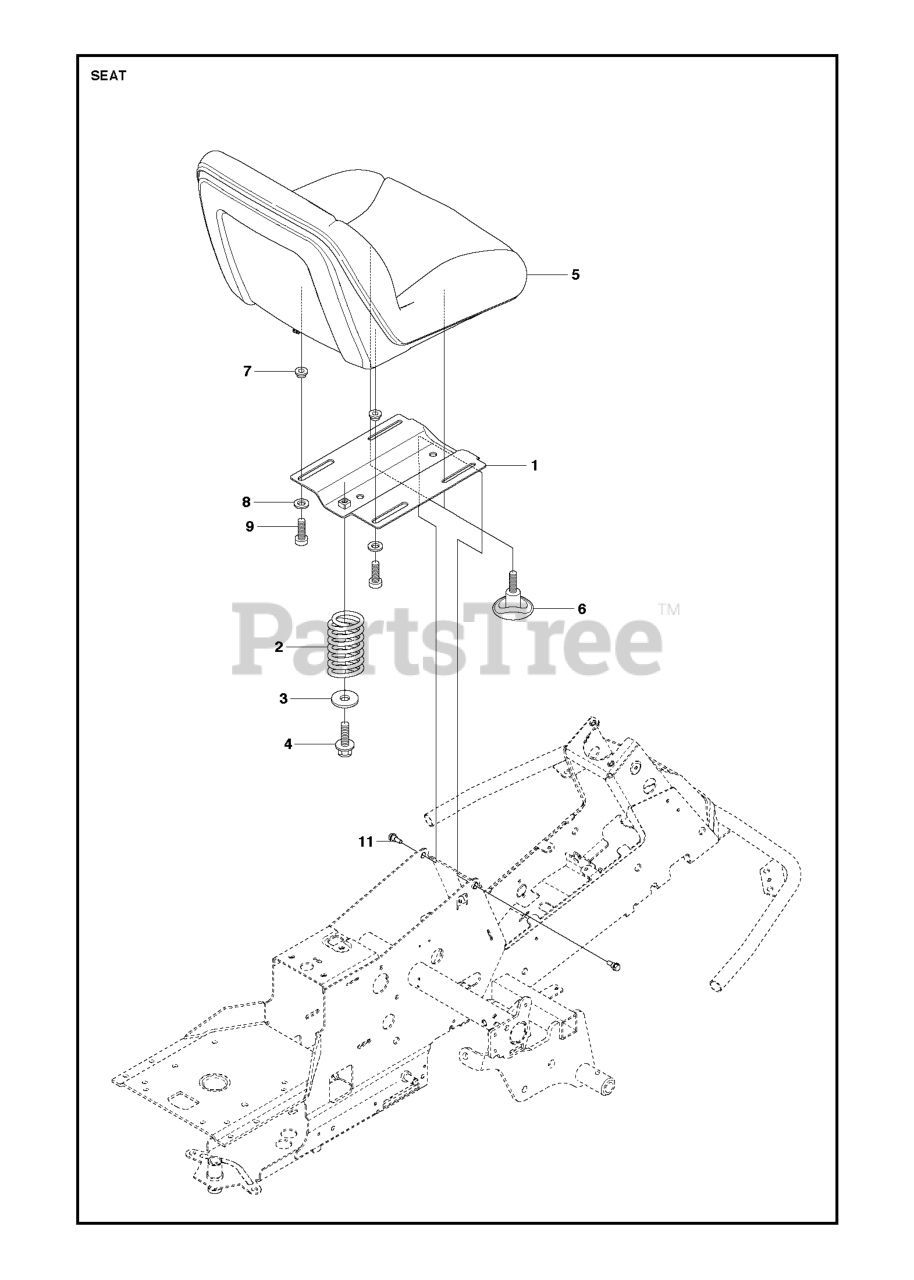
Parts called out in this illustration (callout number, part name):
1	SEAT BRACKET
2	SEAT SPRING
4	Screw M10x25
5	SEAT
6	ADJUSTING KNOB
